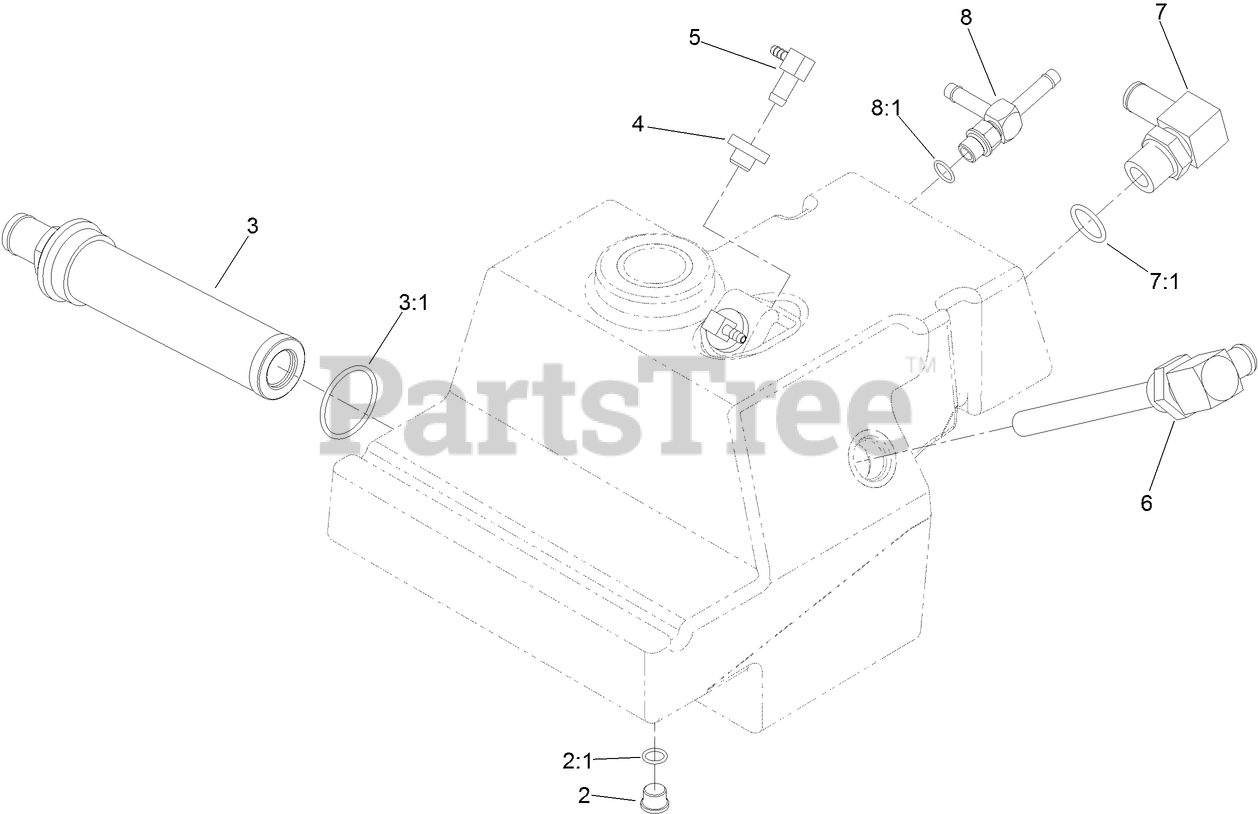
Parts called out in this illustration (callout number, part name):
2	PLUG-HEX, HOLLOW
2:1	O-RING
3	TANK STRAINER ASM
3:1	O-RING
4	BUSHING
5	FITTING-ELBOW, 90 DEG
6	FITTING-STANDPIPE
7	FITTING-ELBOW, 90
7:1	O-RING
8	ADAPTER-RUN, TEE
8:1	O-RING
